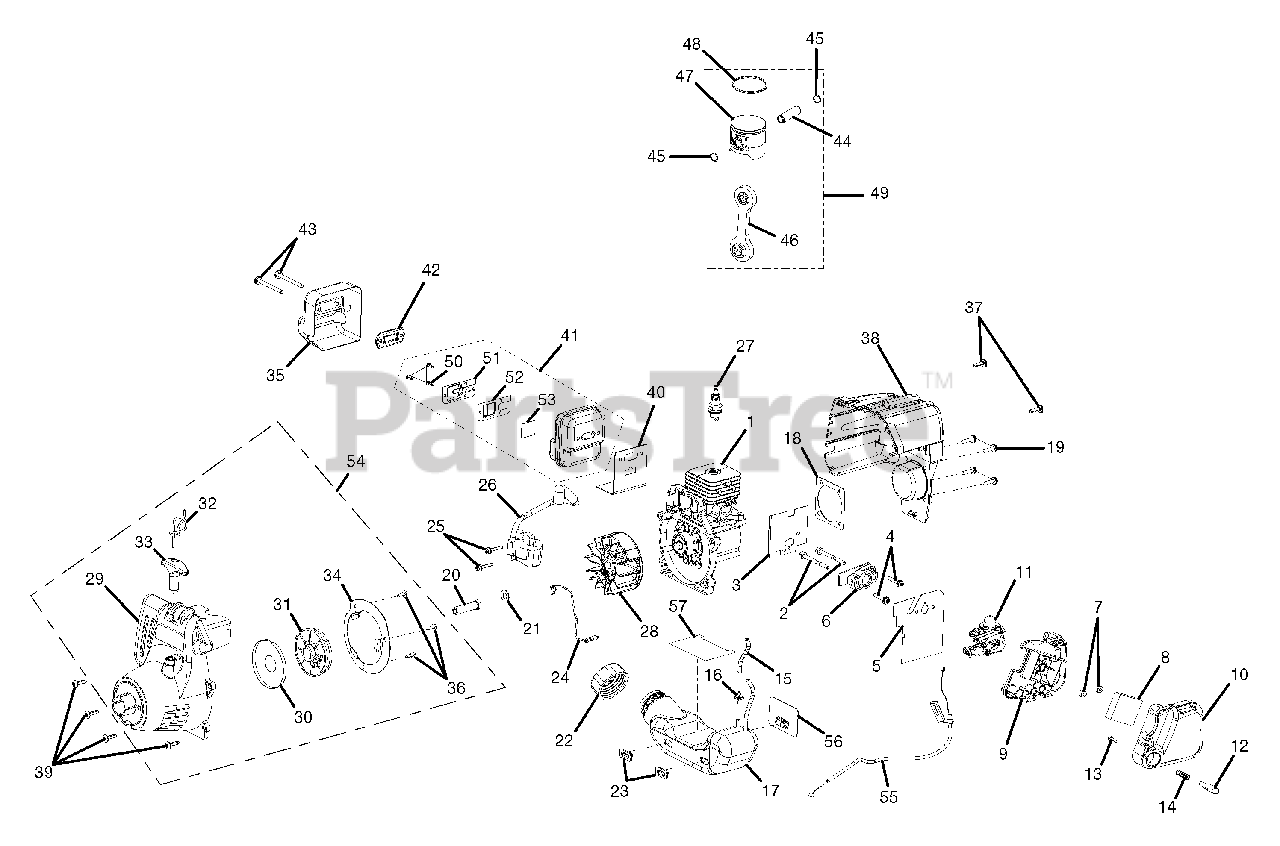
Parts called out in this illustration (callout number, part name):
1	SHORT BLOCK ASSEMBLY (984772001)
2	CARBURETOR BOLTS
3	INTAKE GASKET
4	SCREW (10-24 X 1-1/16 in. PAN HD.)
5	CARBURETOR GASKET
6	HEAT DAM
7	LOCK NUT (10-24)
8	AIR FILTER
9	AIR FILTER BOX
10	AIR BOX COVER
11	CABURETOR ASSEMBLY
12	BUTTON SWITCH
13	SCREW, (6-19 x 1/2 in. T.F.)
14	COMPRESSION SPRING
15	RUBBER TUBING
16	INLINE FUEL FITTING
17	FUEL TANK
18	CRANK CASE COVER GASKET
19	SCREW (10-24 X 3/4 in. PAN HD. TORX W/LW)
20	DRIVE CONNECTOR
21	FLAT WASHER
22	FUEL CAP ASSEMBLY
23	BUMPER (POWER HEAD 984772001)(POWER HEAD 984772003 & 004 QTY 2)
24	LEAD W/TERMINALS
25	SCREW (8-32 X 1 in. THREAD FORMING)
26	IGNITION MODULE
27	SPARK PLUG
28	ROTOR AND PAWL ASSEMBLY
29	STARTER HOUSING ASSEMBLY
30	SPRING AND CONTAINER
31	STARTER PULLEY
32	STARTER ROPE
33	STARTER GRIP
35	HEAT SHIELD (CARB. UNIT)
36	SCREW (8-16 X 1/2 in. THREAD FORMING)
37	SCREW (10-14 X 3/4 in.THREAD FORMING)
38	REAR HOUSING
39	SCREW (10-24 X 3/4 in.TRUSS HD)
40	MUFFLER GASKET
41	NON-CATALYTIC MUFFLER ASSEMBLY
42	REINFORCEMENT PLATE (EPA UNIT)
43	SCREW (10-24 X 2-3/16 in. TORX HD. )
44	PIN, PISTON
45	CLIP RING
46	CONNECTING ROD ASSEMBLY
47	PISTON, 25cc
48	PISTON RING
49	PISTON ASSEMBLY
50	SCREW (6-20 x 1/4 in. PAN HD.)
51	OUTLET TUBE
52	SCREEN PLATE
54	COMPLETE STARTER ASSEMBLY
55	THROTTLE CABLE W/HANGER
56	BUMPER
57	GASKET
